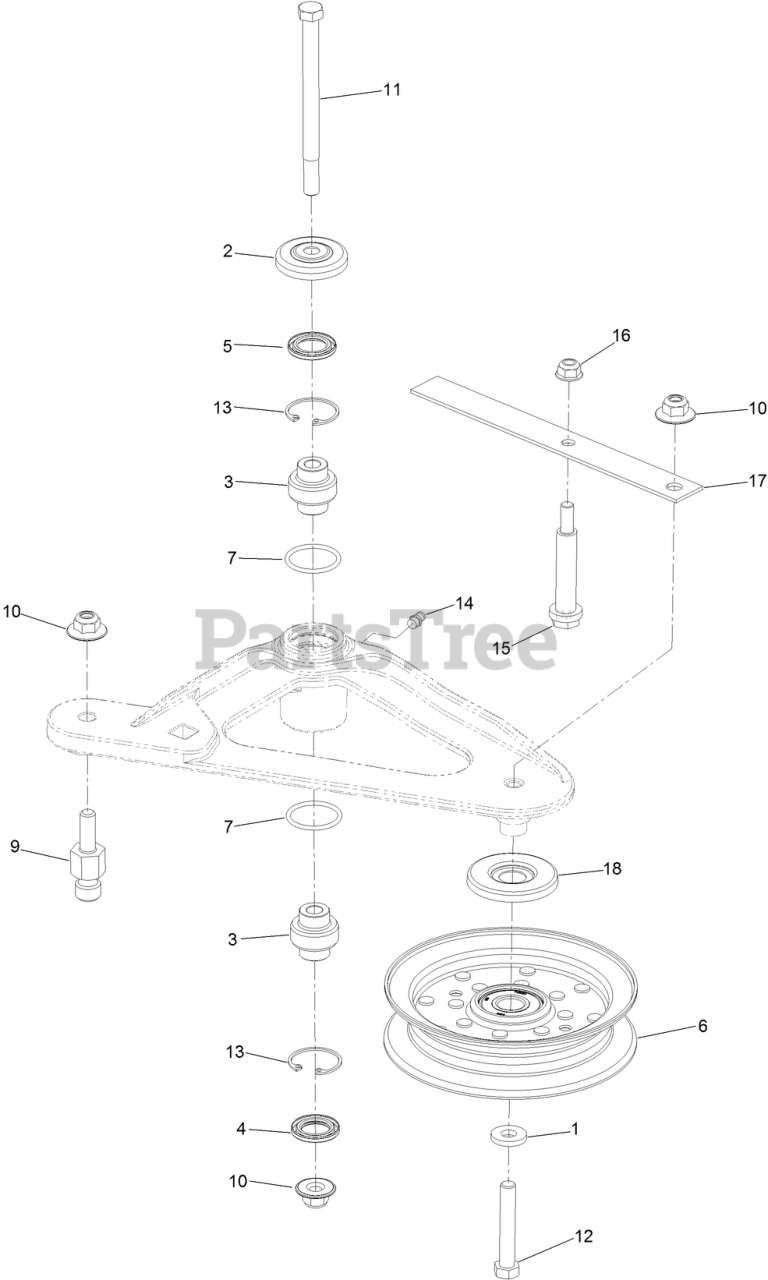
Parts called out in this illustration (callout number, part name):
1	SPACER
2	GUARD-TOP
3	BEARING-SPHERICAL
4	SEAL-LIP, DOUBLE
5	SEAL-LIP, SINGLE
6	IDLER-PULLEY, FLAT
7	O-RING
9	PIN-SPRING, ANCHOR
10	NUT-FLANGE, NI
11	SCREW-SHOULDER, HH
12	SCREW-HH
13	RING-SNAP
14	FITTING-GREASE
15	BOLT-SHOULDER
16	NUT-HF, NI
17	SPRING-BELT
18	SHIELD-GUARD, DUST
